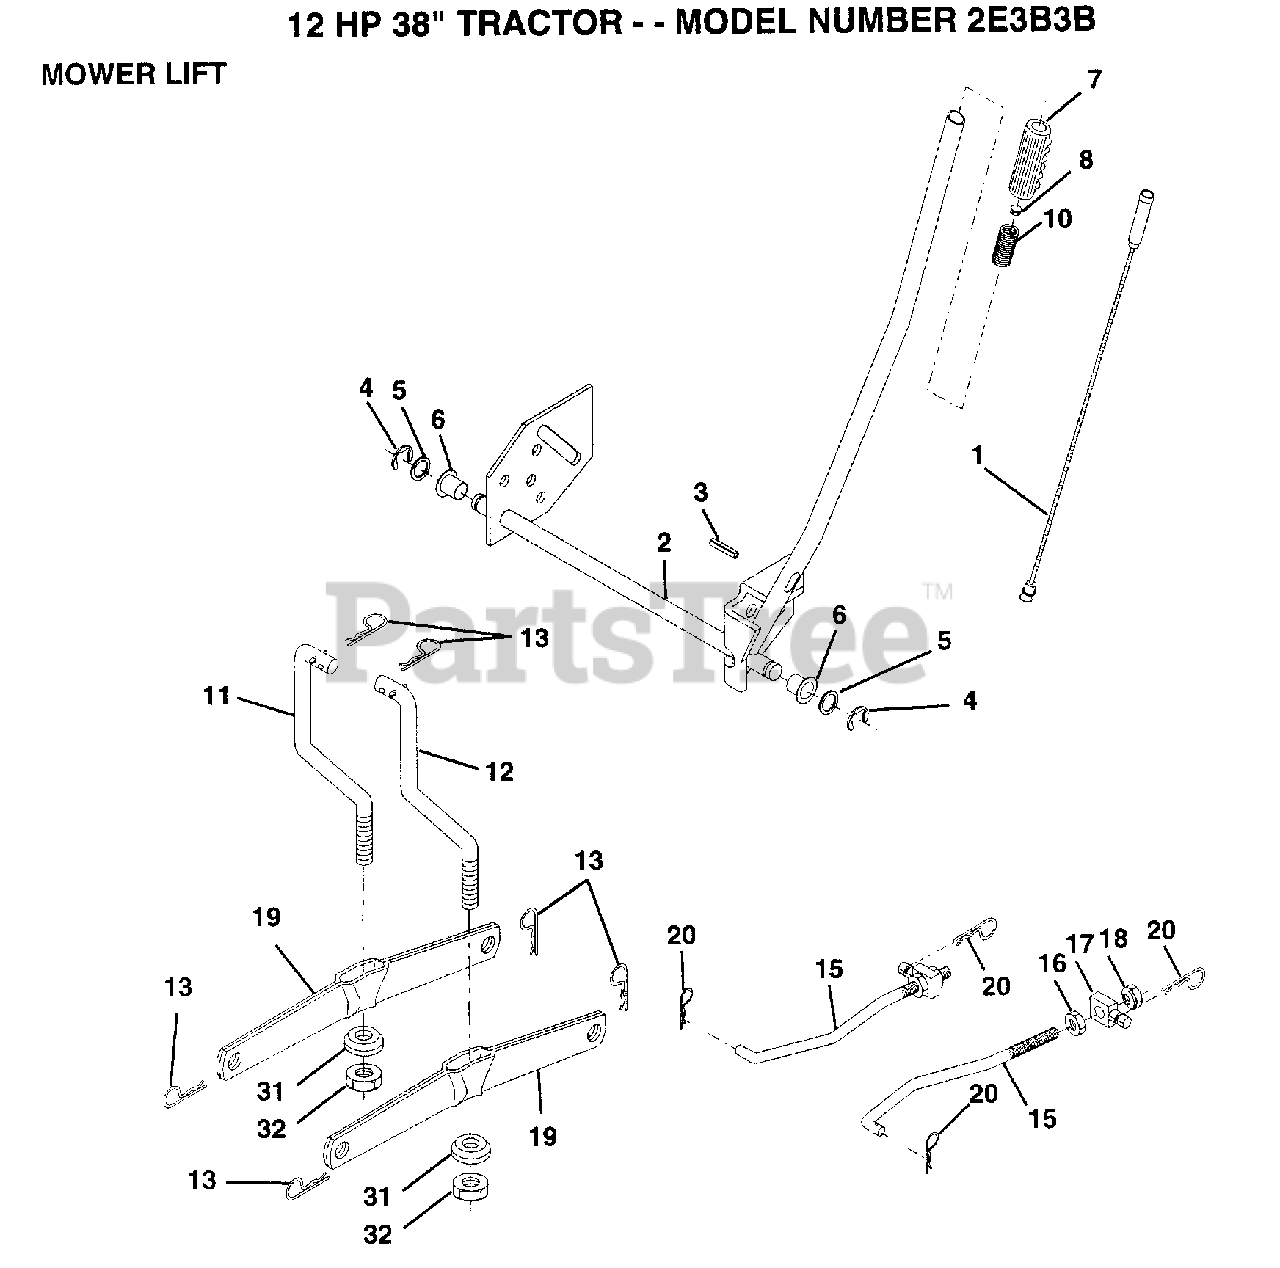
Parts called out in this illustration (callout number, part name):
1	WIRE ASM
3	PIN-GROOVE LT
5	WASHER
6	NYLON BEARING
7	GRIP
15	LINK.FRONT
16	NUT
17	TRUNION
18	NUT.LK.W/WSH.1/2.
19	ARM SUSP REAR
20	RETAINER.SPRING
30	BEARING PVT LH
32	NUT.LOCK.3/8-24
